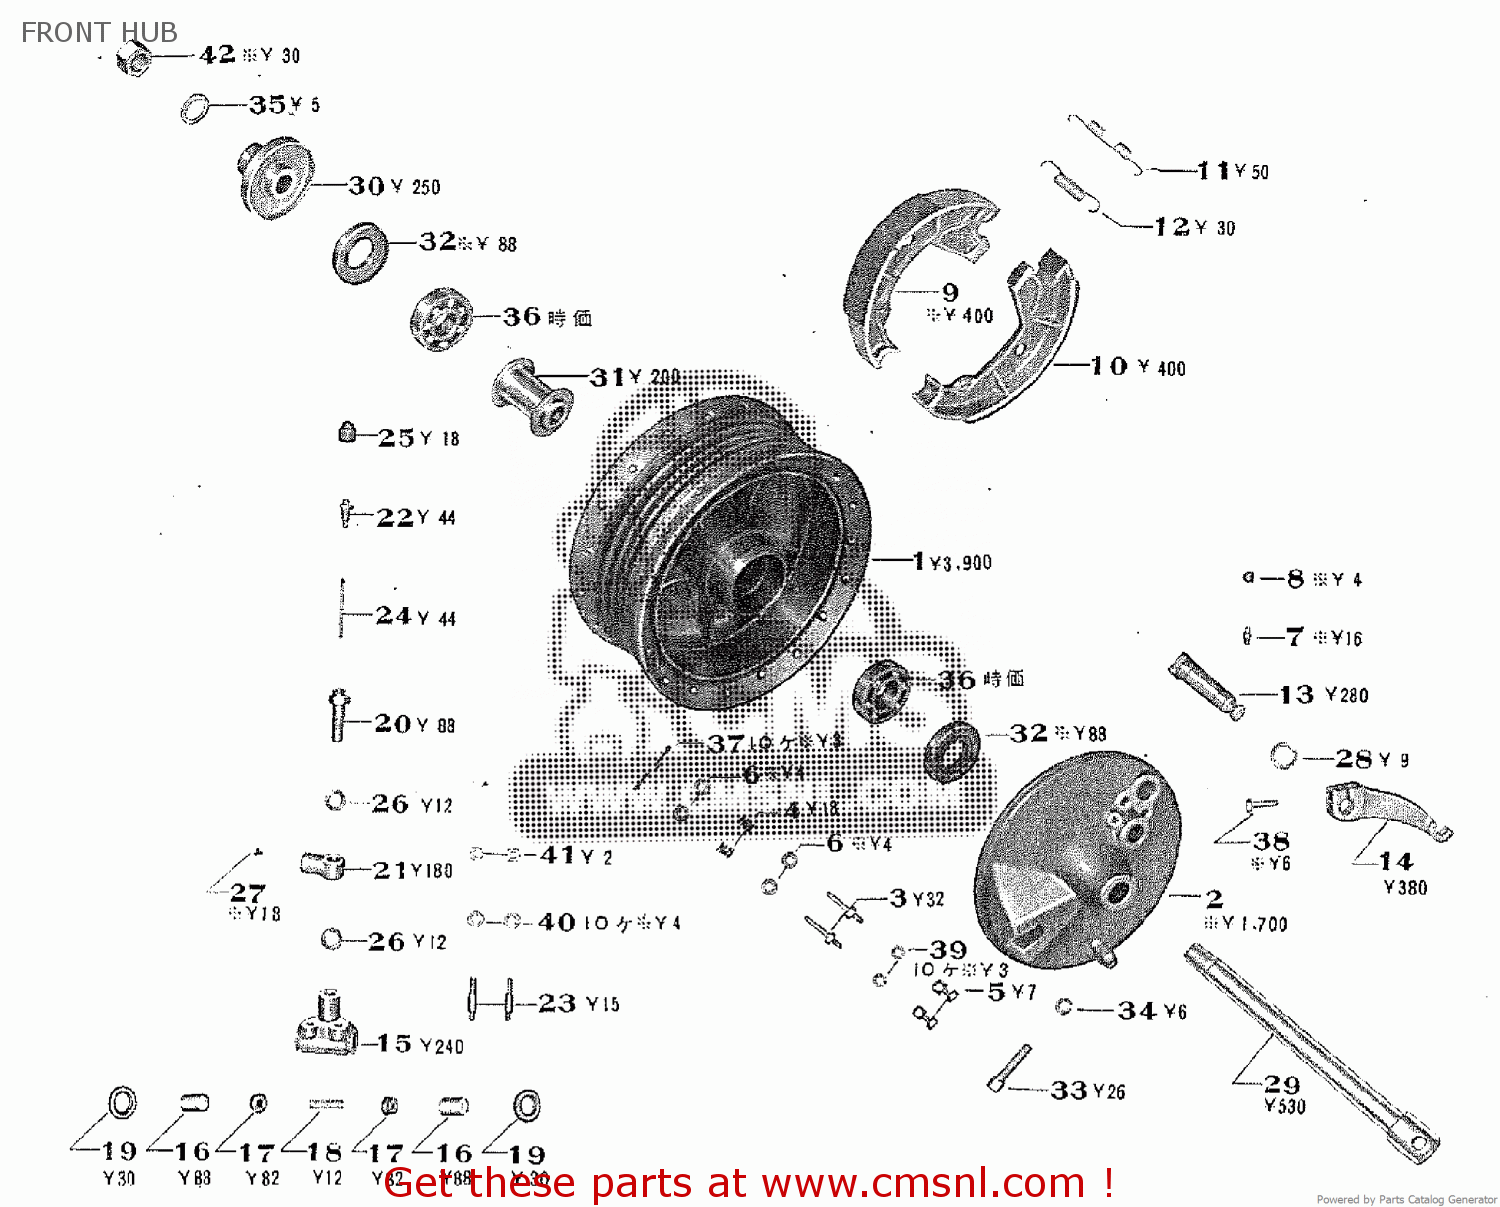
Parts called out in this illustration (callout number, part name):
1	FRONT HUB DRUM COMP.
2	FRONT PANEL COMP.
3	SHOE SUPPORTER SET BOLT
4	SHOE SUPPORTER SPRING
5	SHOE SLIDE PLATE
6	SHOE SUPPORTER SET WASHER
7	GREASE NIPPLE COMP.
8	GREASE NIPPLE CAP
9	TRAILING SHOE COMP.
10	LEADING SHOE COMP.
11	SHOE RETURN UPPER SPRING
12	SHOE RETURN SPRING
13	FRONT BRAKE CAM
14	FRONT BRAKE LEVER
15	FRONT WHEEL CYLINDER
16	PISTON
17	FRONT WHEEL CYLINDER CUP
18	WHEEL CYLINDER SPRING
19	FRONT WHEEL CYLINDER DUST COVER
20	CONNECTOR BOLT
21	WHEEL CYLINDER UNION
22	BLEEDER VALVE
23	WHEEL CYLINDER STUD BOLT
24	WHEEL CYLINDER BLEEDER PIPE
25	BLEEDER VALVE CAP
26	UNION PACKING
27	TUBE JOINT SHEET
28	FRONT BRAKE CAM WASHER
29	FRONT HUB SHAFT COMP.
30	FRONT HUB COLLAR
31	FRONT BEARING DISTANCE COLLAR
32	HUB DRUM OIL SEAL
33	BRAKE WIRE ADJUSTER
34	BRAKE WIRE ADJUSTER NUT
35	FRONT HUB SHAFT SET WASHER
36	BALL BEARING
37	2.0X12 COTTER PIN
38	6X18 HEXAGON BOLT
39	5MM SPRING WASHER
40	6MM SPRING WASHER
41	6MM HEXAGON NUT
42	16MM LIGHT HEXAGON NUT
